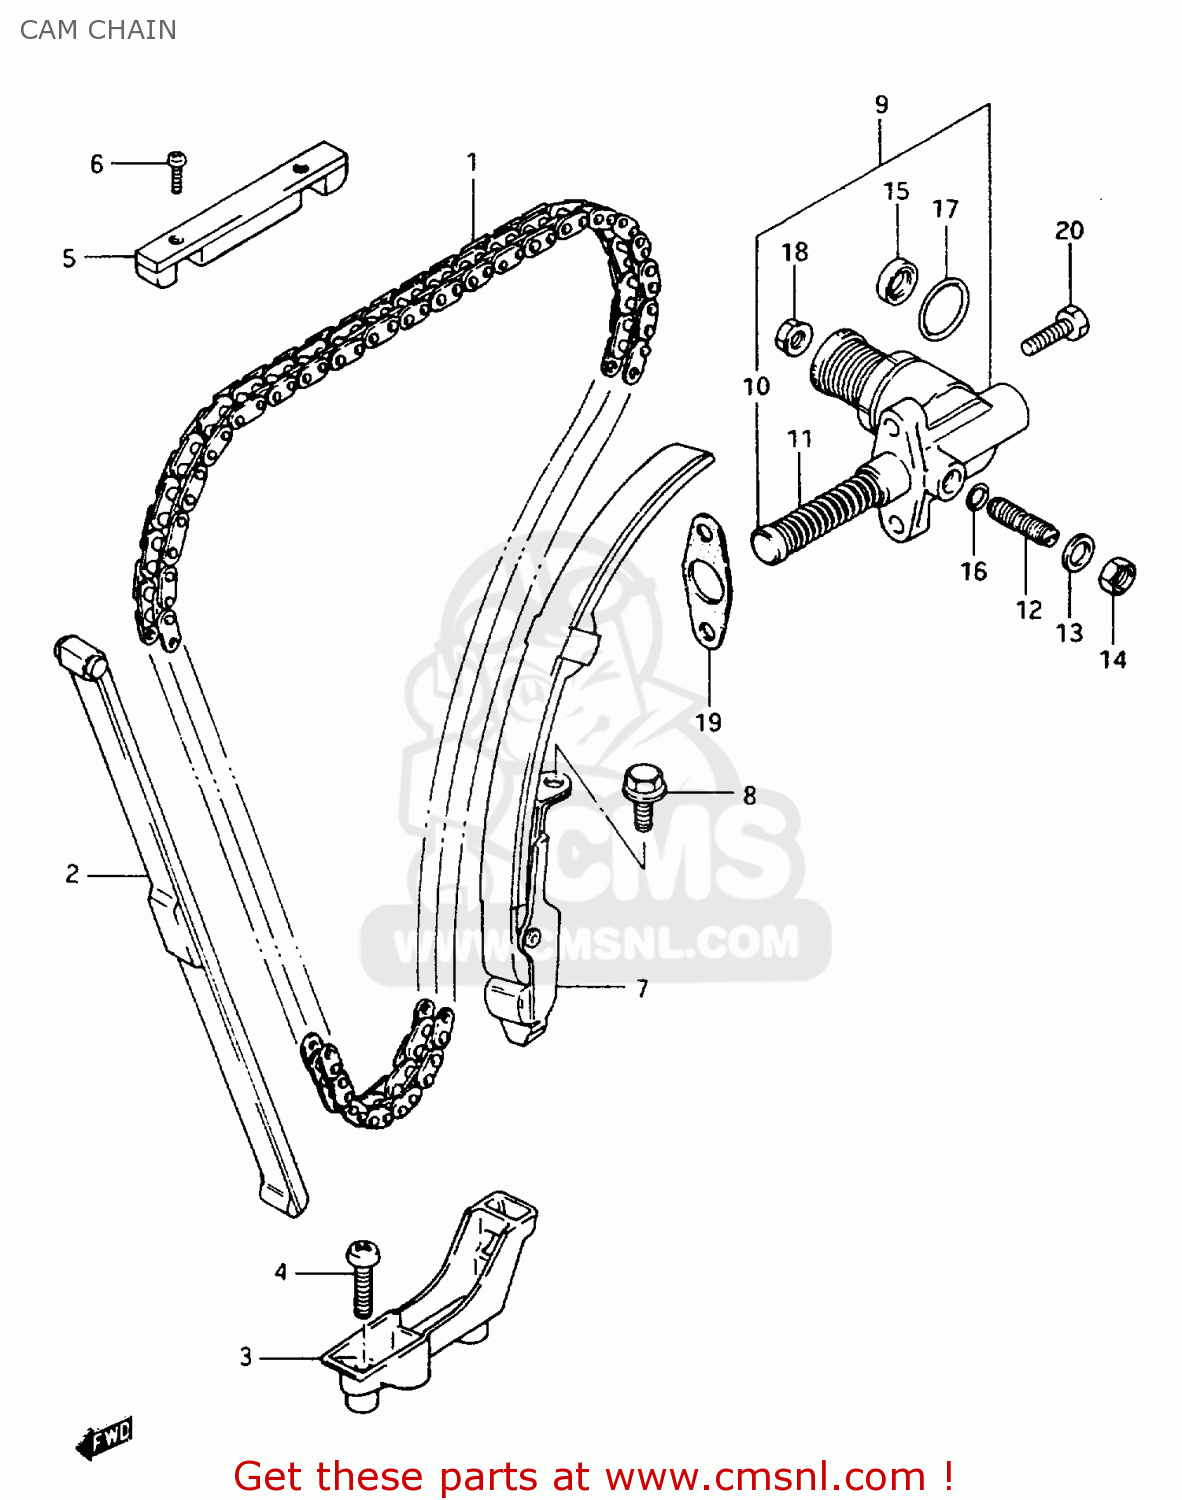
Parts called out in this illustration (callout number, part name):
1	CHAIN,CAMSHAFT DRIVE
2	GUIDE,CAM CHAIN NO.1
3	HOLDER,CAM CHAIN GUIDE
4	SCREW
5	GUIDE,CAM CHAIN
6	SCREW
7	TENSIONER,CAM CHAIN
8	BOLT
9	ADJUSTER ASSEMBLY,TENSIONER
10	ROD,PUSH
11	SPRING
12	SCREW,TENSIONER ADJUST
13	WASHER
14	NUT
15	SEAL,OIL(10X16X4)
16	O RING(D:1.9,ID:5.7)
17	O RING(D:2.4,ID:20.8)
18	NUT 6MM
19	GASKET,TENSIONER ADJUSTER (MCA)
20	SCREW
